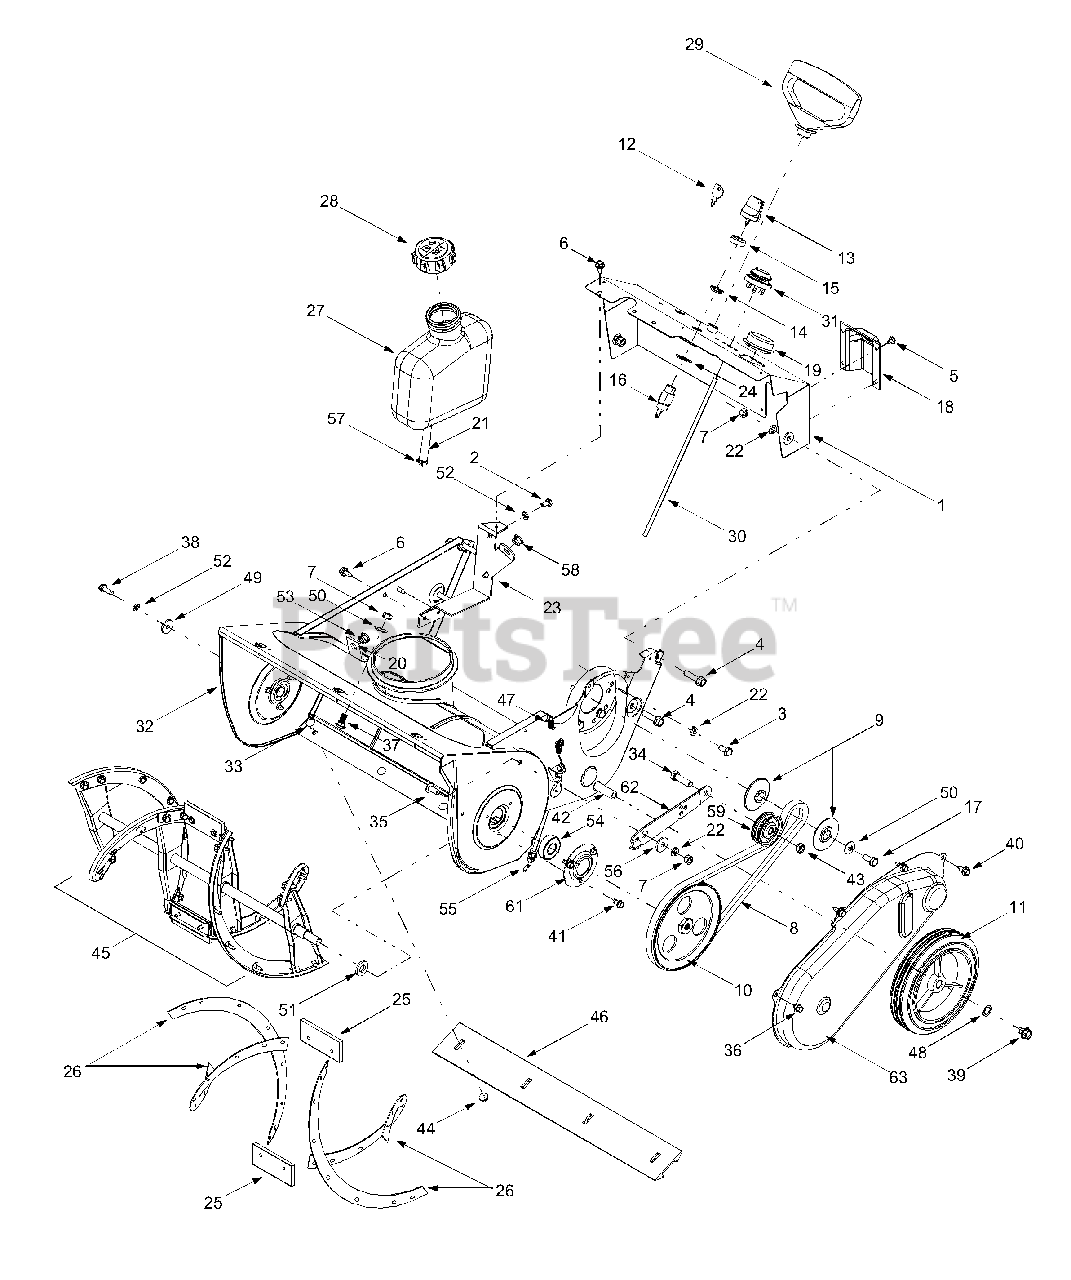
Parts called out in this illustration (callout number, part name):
3	Hex Cap Screw, 5/16-24 x .625
4	Hex Flange Screw, 5/16-18 x 1.25
5	Screw, #10-16 x .375
6	Self-tapping Screw, 1/4-20 x .625
7	Hex Nut, 5/16-18
8	Drive Belt
9	Pulley Half-.625 x 2.25
10	Auger Drive Pulley
11	Wheel Assembly, 7 x 1.5
12	Ignition Key
13	Ignition Key w/ Plastic Cover
14	Ignition Nut, 5/8-32
15	Ignition Switch Cap
16	Ignition Switch
17	Hex Cap Screw, 5/16-24 x .75
18	Choke Cover
19	Spark Plug Cap
20	Chute Crank Bracket
21	Fuel Line Hose
22	Lock Washer, 5/16
23	Fuel Tank Support Bracket
24	Internal Lock Washer, 5/8 x 1.058 x .046
25	Rubber Paddle
26	Rubber Paddle/Spiral
27	Gas Tank, 2 qt.
28	Fuel Cap (50:1 Red Print)
29	Recoil Handle (Mitten Grip)
30	Primer Tube
31	Primer Bulb
34	Cap Screw, 3/8-24 x 1.25
35	Trus Machine Screw, 5/16-18 x .75
36	Hex Index Washer Screw, 1/4-14 x .375
37	Carriage Bolt, 5/16-18 x .75
38	Self-tapping Screw 1/4-20 x .75
39	Self-tapping Screw 3/8-16 x .50
40	Self-tapping Screw, 1/4-14 x .625
41	Self-tapping Screw, 1/4-14 x .50
42	Axle, .35 x .5 x 20.75
43	Jam Lock Nut, 3/8-24
44	Hex Flange Lock Nut, 1/4-20
45	Solid Shaft Auger Assembly
46	Shave Plate, 2.66 x 19.88
47	Extension Spring, .33 x 1.12
48	Flat Washer, .51 x .75 x .033
49	Flat Washer, .265 x .938 x .120
50	Belleville Washer, .340 x .872
51	Flat Washer, .51 x 1.0 x .125
52	Lock Washer, 1/4
53	Plastic Bushing
54	Ball Bearing, 17mm x 40mm x 12mm
55	Cable, 41.78"
56	Shoulder Spacer
57	Hose Clamp, .49
58	Plastic Bushing, .38
59	Flat Idler Pulley, 1.88 x .50 x 2.12
60	Hi-Lo Self-tapping Screw, 1/4-15 x .75
61	Bearing Cup
62	Brake Idler Bracket
